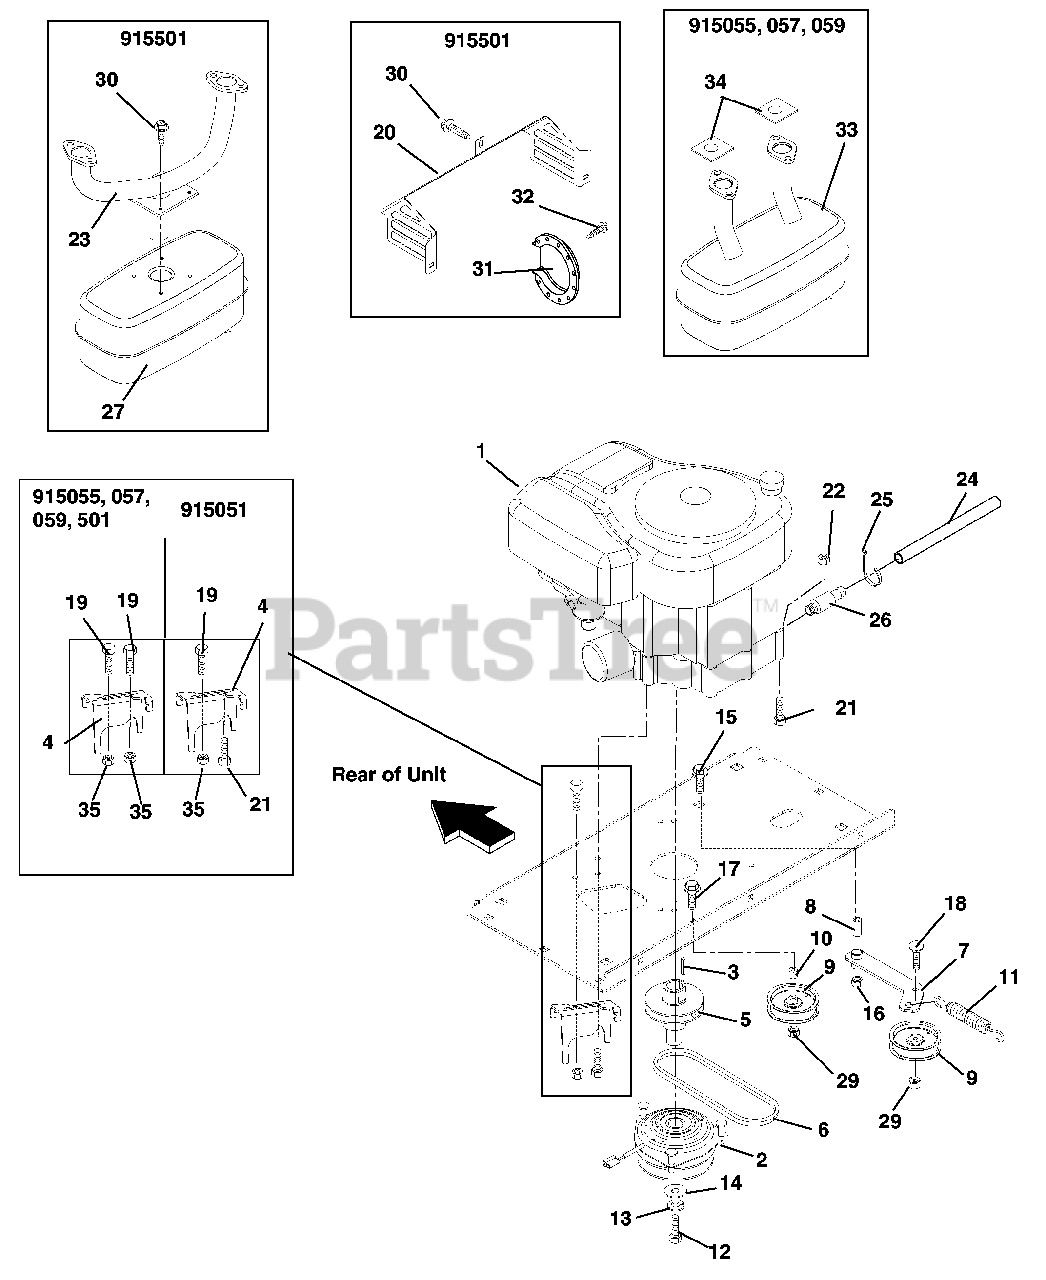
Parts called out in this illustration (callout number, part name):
1	ENGINE GROUP - 16HP
1	SERVICE ENGINE,21 HP KOHLER
1	SERVICE ENGINE,23 HP KOHLER
1	ENGINE GROUP - 18HP
2	CLUTCH, ELECTRIC
3	KEY-SQ .25 X 1.50 X .25 SAE
4	STOP, CLUTCH
5	EXTENSION SHAFT
6	BELT,HA WRAPPED
7	WMT, IDLER
8	BSHG-SLV .500X.750X1.560
9	IDLER-FLAT 4.00 X .38 NWHAMSHR
10	BSHG,SPCR .41 X .75 X .88 PM
11	SPRING, EXT
12	BLT-HEX .44-20X4.50 GR8 YWZC
13	@WSHR-LK .44X.109 REG YWZC
14	WSHR-FL-STL .469X2.00X.25 YWZC
15	@BLT-HEX .50-13X2.50 GR5 YWZC
16	@NUT-LK-TOP-FLG .50-13 YWZC
17	@BLT-RDHDSQNK .38-16X2.00 G5YZ
18	@BLT-RDHDSQNK .38-16X1.25 G5YZ
19	@BLT-HEX .38-16X1.00 GR5 YWZC
20	MUFFLER GUARD, 40CI
21	@BLT-HEX .31-18X1.75 GR5 YWZC
22	@NUT-LK-NYL-FLG .31-18 YWZC
23	PIPE, EXHAUST
24	TUBE, OIL DRAIN
25	CABLE TIE LG 5-1/2
26	VALVE, OIL DRAIN
27	MUFFLER - EXHAUST
28	@BLT-HEX .31-18X1.75 GR5 YWZC
28	@SCR-TAP .38-16X1.00 HWH TR YZ
29	@NUT-LK-CTR-JAM .375-16 YWZC
30	@SCR-TAP .25-20X.50 HWH TR YWZ
31	DEFLECTOR B+S 222573
32	SCR-TAP 8-32X.38 SL HWH YWZC
33	MUFFLER
34	SHEET-HEAT REFLECTIVE 3X5
35	@NUT-LK-NYL-FLG .38-16 YWZC
